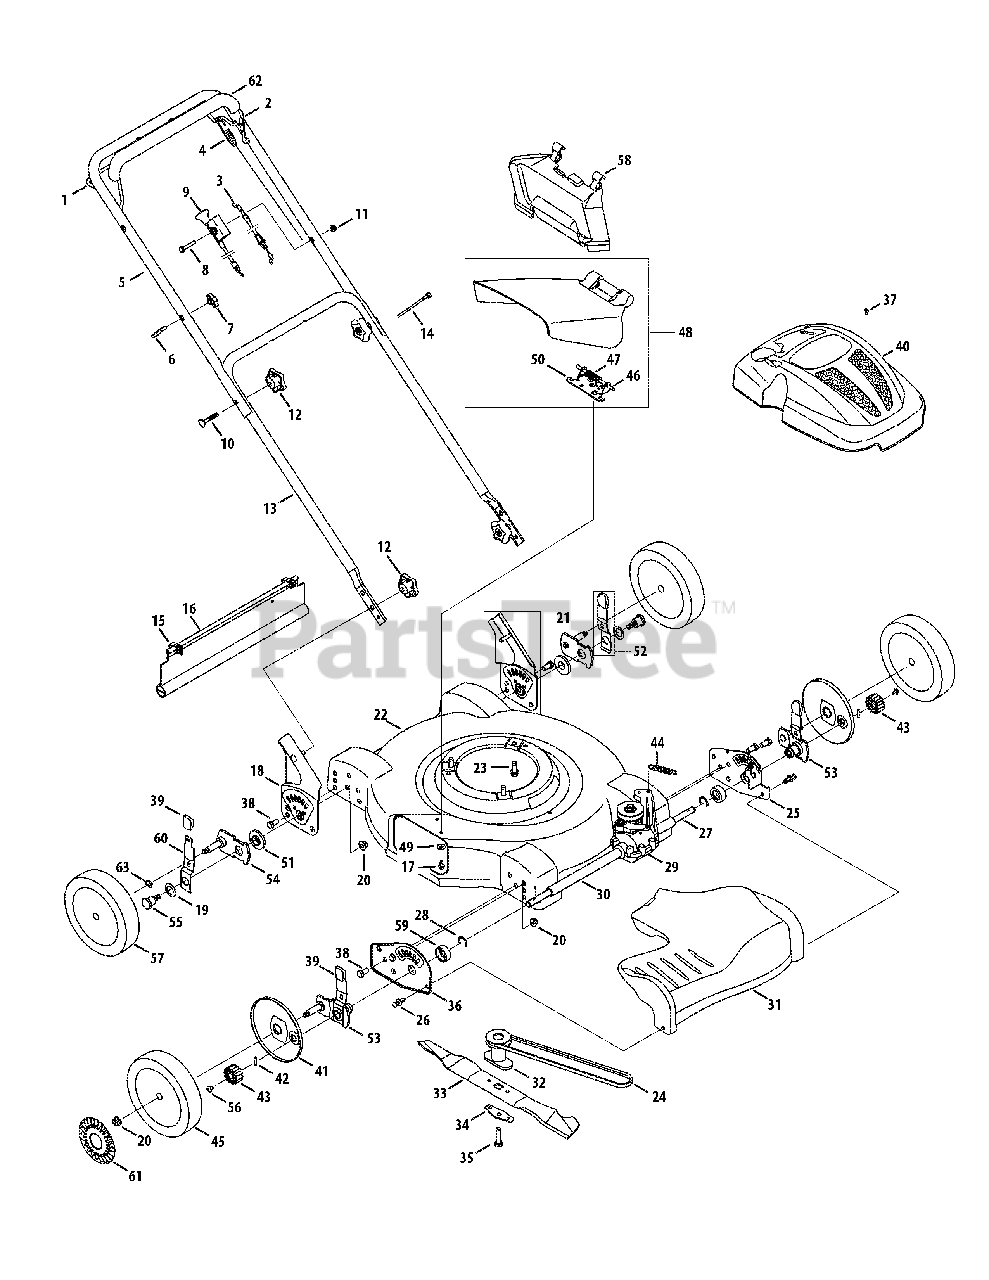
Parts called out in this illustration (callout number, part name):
1	Drive Control
3	Blade Control Cable
4	Drive Control Cable
6	Eye Bolt
7	Wing Nut, 1/4-20
8	Hex Screw, 1/4-20 x 1.50
9	Choke Cable
10	Carriage Bolt, 5/16-18 x 2.0
11	Flange Lock Nut, 1/4-20
12	Star Knob
14	Cable Tie
15	Hinge Clip
16	Trail Shield
17	Hex Screw, 1/4-20 x.500
20	Lock Nut, 3/8-16
23	Hex Washer Scr., 3/8-16 x 1.0
24	V-Belt, 3L x 32.90
26	Rivet
27	Sleeve Spacer, .550 ID x 2.22
28	Retainer Ring
29	Transmission Assy. Comp.
30	Sleeve Spacer, .550 ID x 8.51
31	Transmission Cover (Yellow)
32	Blade Adapter
33	22" Mulching Blade
34	Blade Bell Support
35	Hex Cap Screw, 3/8-24 x 1.5
37	Machine Screw, M4X.7
38	Hex Cap Screw, 3/8-16 x.75
39	Adjustment Knob
40	Engine Shroud (Yellow)
41	Wheel Dust Cover
42	Pin
43	Spur Gear 14T - RH
43	Spur Gear 14T - LH
44	Ext. Spring, .47 OD x 2.50
45	Front Wheel, 8 x 1.8
45	Front Wheel, 8 x 2.125
46	Hinge Pin
47	Torsion Spring
48	Side Discharge Assembly
49	Bell Washer, .265 ID x.75 OD
50	Deflector Chute Adapter
51	Height Adjustment Bearing
52	Rear Hgt. Adj. Lever Assembly
53	Front Lever Assembly
54	Rear Pivot Arm Assembly
55	Shoulder Screw, 3/8-16
56	Screw, 1/4-20 x .390
57	Rear Wheel, 8 x 1.8
57	Rear Wheel, 8 x 2.125
58	Mulching Baffle
59	Bearing Support Spacer
60	Spring Lever
61	Hub Cap
62	Deluxe Bail Cover
63	Washer, Wave, .510 x .750 x .017
